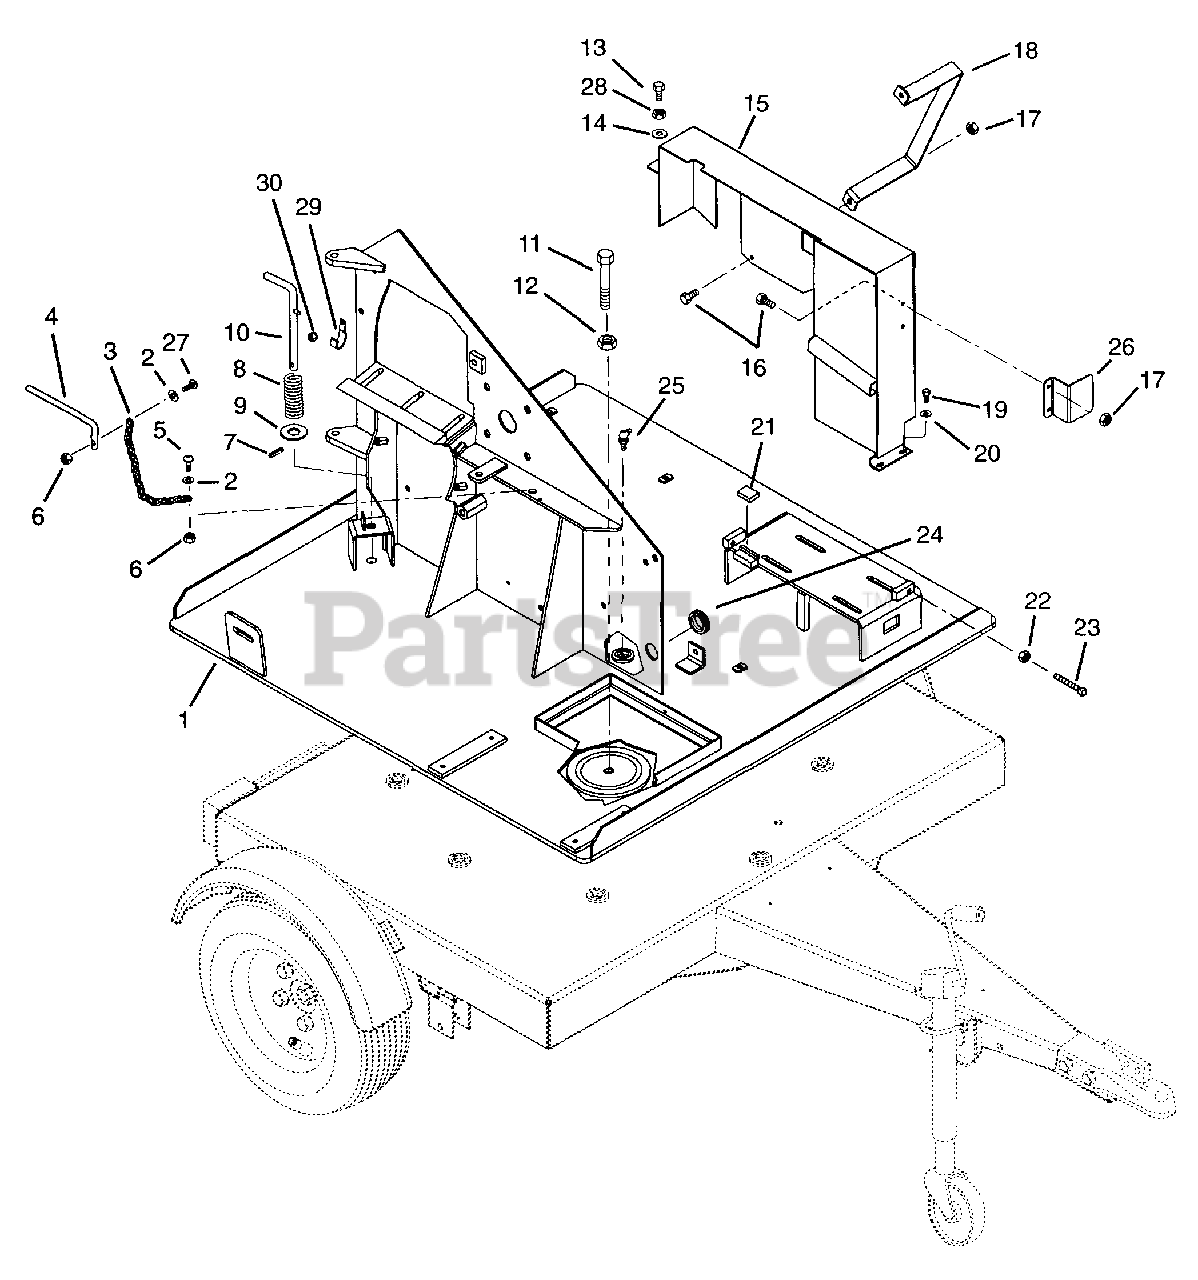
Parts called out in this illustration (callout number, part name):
1	Base Weldment-Rotating
2	Washer-Flat-Steel .219 x .50 x .049
3	Chain-14 Straight Link #4
4	Lock Handle
5	Screw-Machine 10-24 x 1.00 HWH
6	Nut-Locking-Nylon 10-24 w/Insert
7	Pin-Roll .188 X 1.50
8	Spring-Compression .08 X .91 X 3.38
9	Washer-Flat-Steel .656 X 1.312 X .095
10	Pin-Index
11	Bolt-Hex .75-16 X 2.50 Grade 5
12	Nut-Locking-Center .75-10
13	Bolt-Hex .31 x .875 x .083
14	Washer-Flat-Steel .38 x .875 x .083
15	Guard-Belt Weld Assembly
16	Bolt-Hex .31-18 x .50 Grade 5
17	Nut-Locking-Center .31-18
18	Guard-Muffler
19	Bolt-Hex .38-16 x .75 Grade 5
20	Washer-Locking .38-.094
21	Key
22	Nut-Hex .38-18
23	Bolt-Hex .38-16 x 3.50
24	Grommet .125 x 1.000 ID
25	Fitting- Drive Hydraulic
26	Guard-Manifold
27	Screw-Machine 10-24 x 1.00
28	Nut Hex .31 18
30	Nut-Locking-Center .38-16
